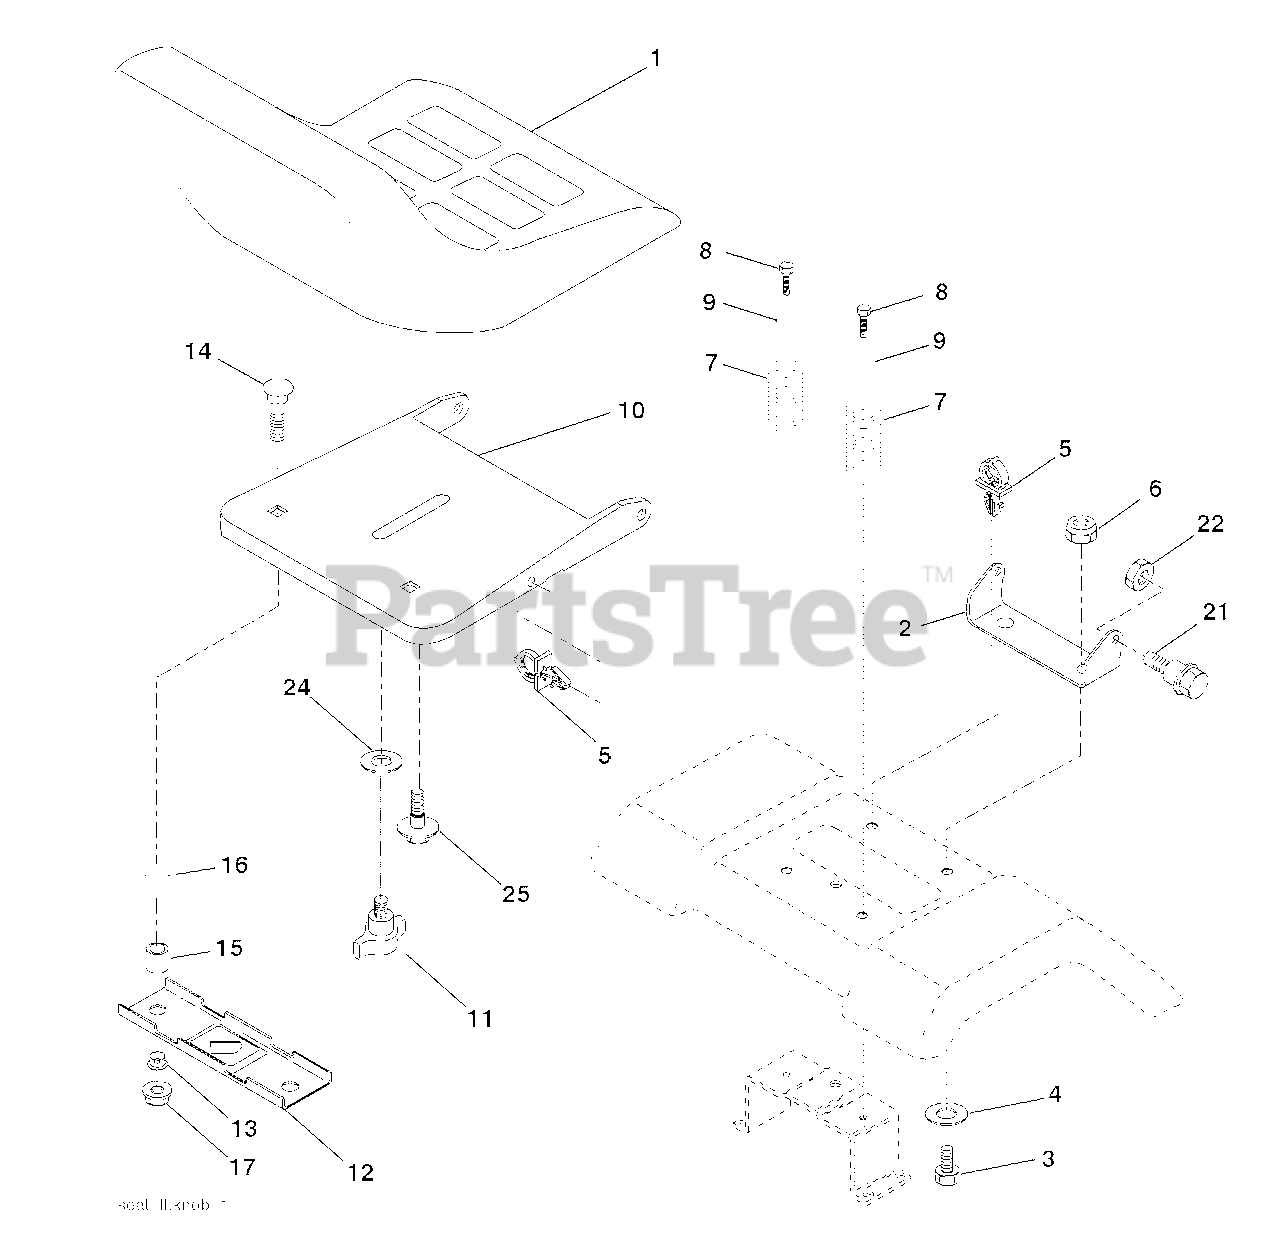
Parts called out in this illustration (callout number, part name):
1	Seat
2	Bracket Pivot Seat 8 720
3	Bolt Fin Hex 3/8-16 unc x 1
4	Washer 13/32 x 1 x 10 Ga.
5	Clip Push-In
6	Nut Hex w/Ins. 3/8-16 unc
7	Spring Seat Cprsn 2 250 Blk Zi
8	Screw 3/8-16 x 1-1/2 Smgml Tap/R Z
9	Washer 13/32 x 1 x 14 Ga.
10	Pan Seat
11	Knob Seat Adj. Wingnut
12	Bracket Mounting Switch
13	Bushing Snap Blk Nyl 50 Id
14	Bolt Rdhd Sqnk 1/4-2 x 1-1/2
16	Spring Cprsn
17	Nut Lock 1/4 Lge Flg Gr. 5 Zinc
21	Bolt Shoulder 5/16-18 unc-2a Blk DA
22	Nut Hex Lock W/Ins 5/16-18
24	Washer 17/32 x 13/16 x 12 Ga.
25	Bolt Shoulder 5/16-18 x 62
